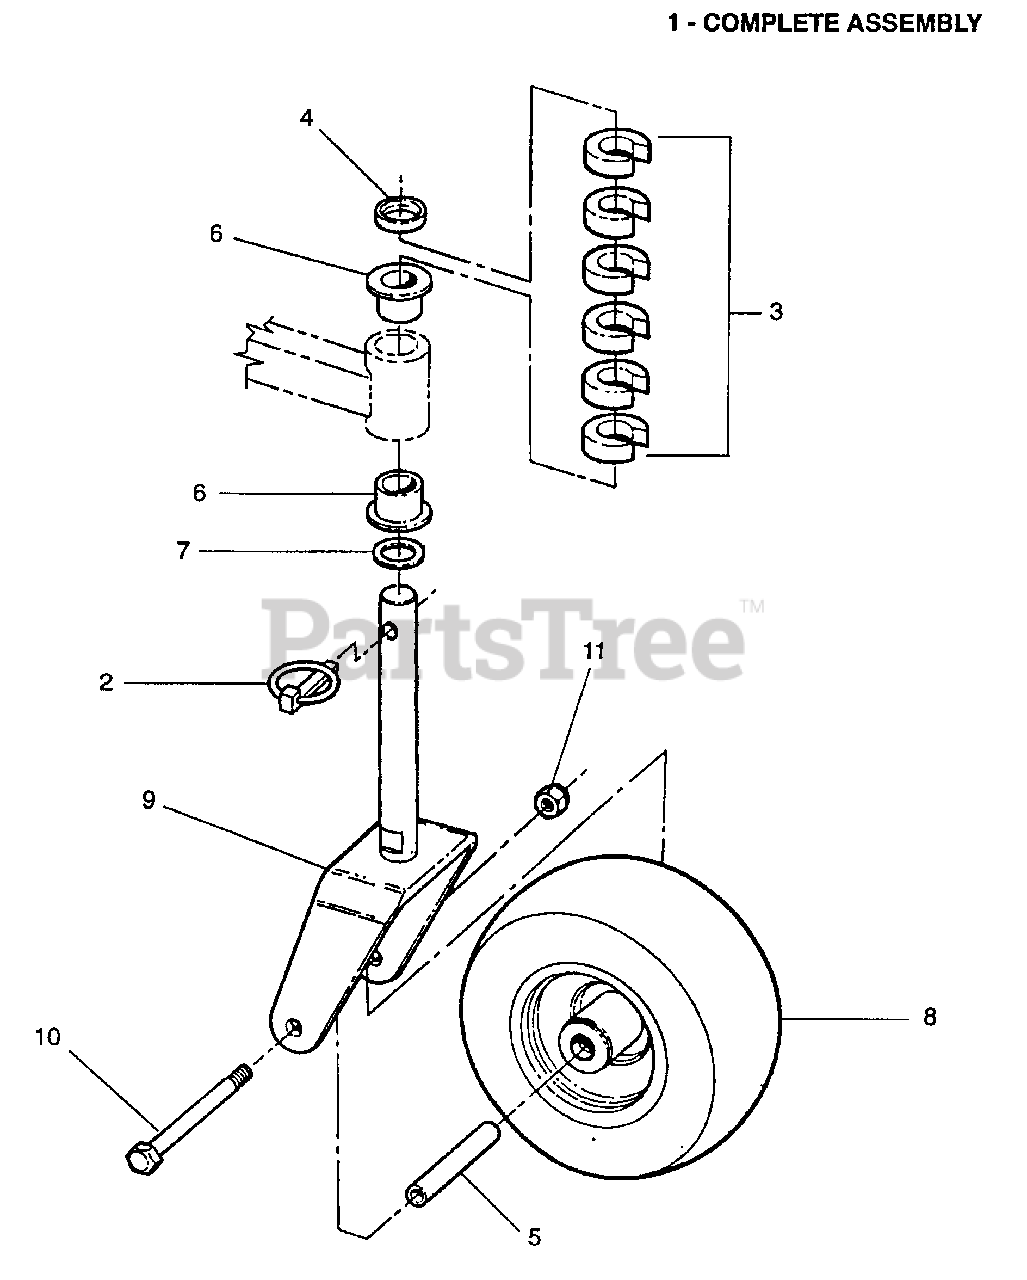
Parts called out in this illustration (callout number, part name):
1	ASSEMBLY, Caster, 73" Finishing Deck
2	PIN, 6/16" Lynch
3	SPACER, Caster
4	SPACER, 1" x 1 3/8 x .30" (PM)
5	SPACER, Axle Sleeve
6	BUSHING, Caster
7	BUSHING, 1" Machine
8	ASSEMBLY, Wheel/Tire 9 x 3.50-4
9	YOKE, Caster (Weldment)
10	BOLT, 1/2-13 X 5-1/2" GD5 YZ
11	NUT, 1/2-13 HEX NYLON LOCK
